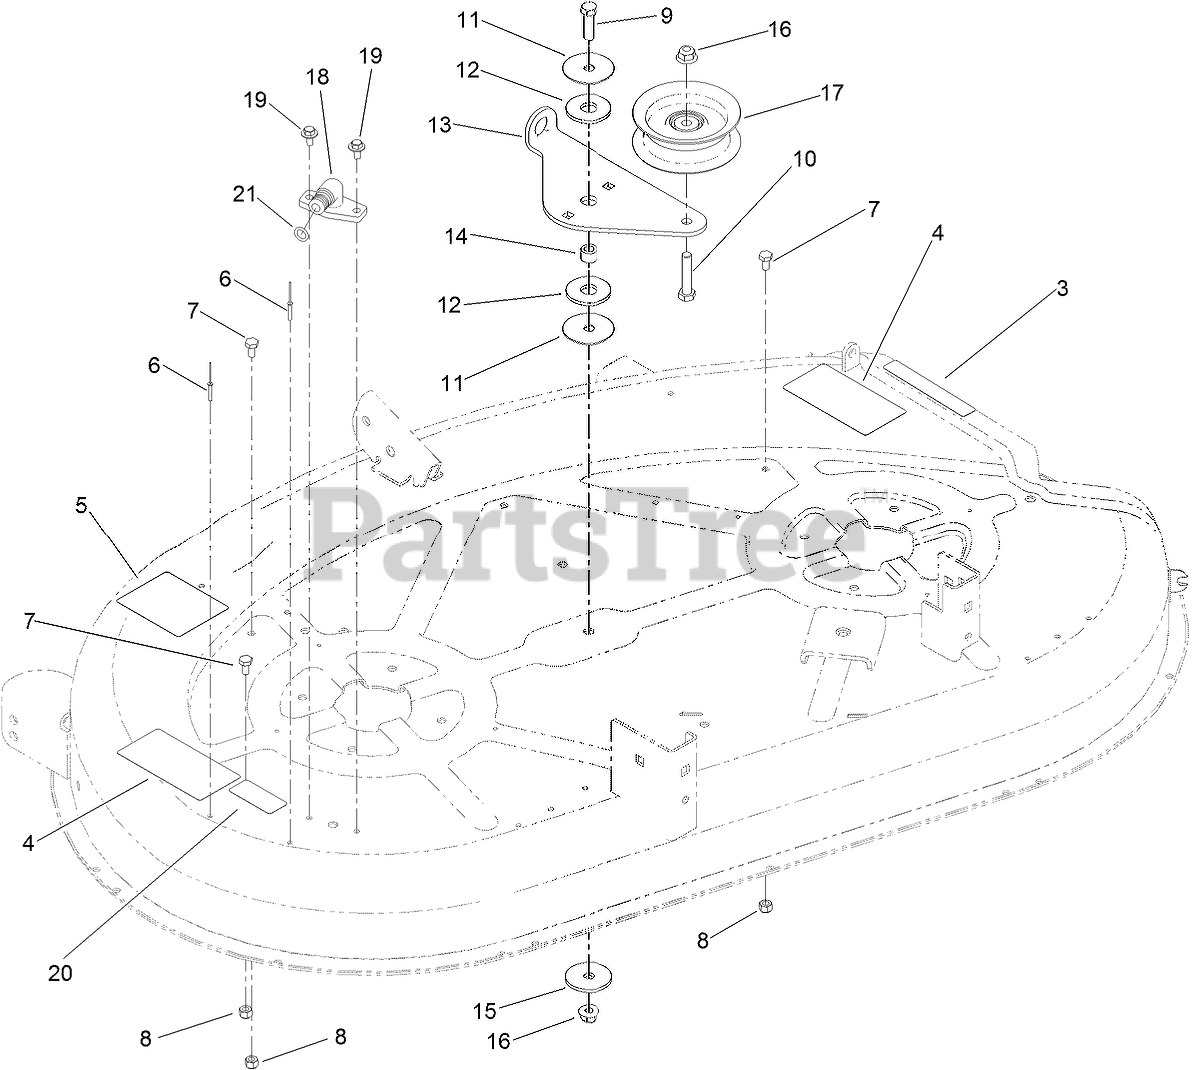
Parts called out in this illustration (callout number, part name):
3	DECAL-DANGER
4	DECAL-DANGER, DECK
5	DECAL-ROUTING, BELT
6	RIVET-BLIND
7	SCREW-HH
8	NUT-LOCK, NI
9	SCREW-HH
10	SCREW-HH
11	WASHER
12	WASHER-FRICTION, COMPOSITE
13	ARM-IDLER
14	SPACER
15	WASHER-REBOUND
16	NUT-HF, NI
17	PULLEY-IDLER, FLAT
18	FITTING-WASHOUT
19	SCREW-HHFTF
20	DECAL-SERVICE
21	O-RING
